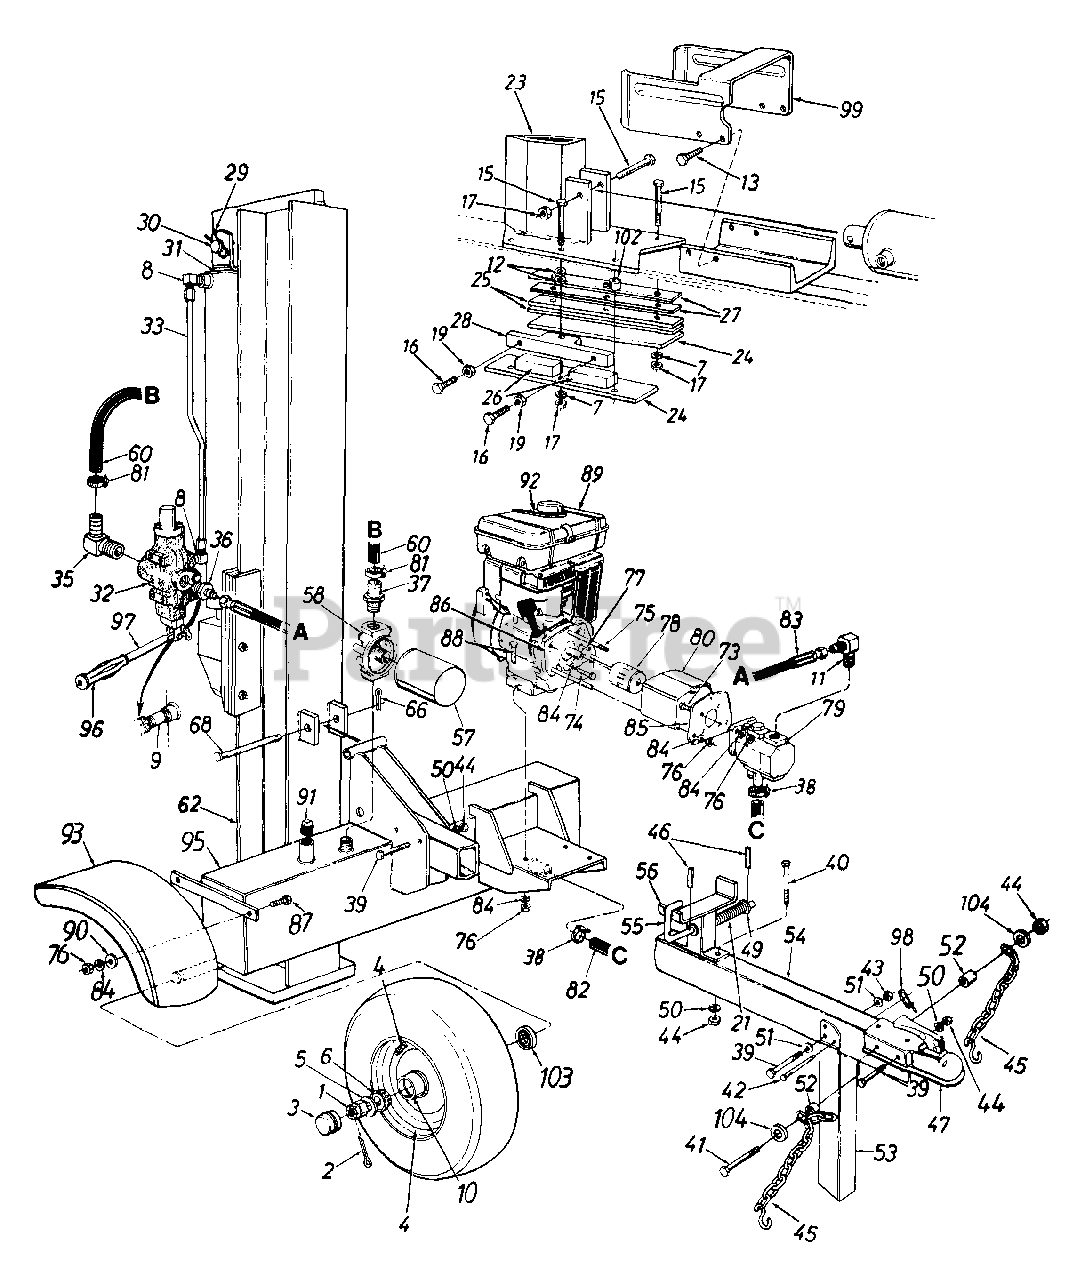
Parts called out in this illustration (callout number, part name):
1	Slotted Nut 3/4-16 Thd.
2	Cotter pin 5/32" Dia.
3	Hub Cap
4	Wheel Ass'y. Comp.
4	Tire Only
4	Rim Only
4	Air Valve Only
5	Fl-Wash. .76" I.D. x 1.5" O.D.
6	Bearing Cone
7	L-Wash. 1/2" I.D.
8	90° Solid Male Adaptor
9	Pipe Nipple 1/2 NPT
10	Bearing Cup
11	90° Male Adapter
12	Fl-Wash. .531" I.D. x .94" O.D.
13	Hex Cap Scr. 3/8-16 x 1" Lg.
15	Hex Bolt 1/2-20 x 2.75" Lg. (Grade 8)
16	Hex Bolt 3/8-24 x 1.5" Lg.
17	Hex L-Nut 1/2-20 Thd.
19	Hex Jam Nut 3/8-24 Thd. (Grade 5)
21	Comp. Spring 4" Lg.
23	Wedge Ass'y.
27	Adjustable Gib Shim
29	External Cotter Pin
30	Cylinder Mounting Pin
31	Hydraulic Cylinder
32	Control Valve
33	Metal Pressure Tube
35	Return Elbow
36	Adapter
37	3/4" Hose Barb.
38	Hose Clamp
39	Hex Bolt 3/8-16 x 3" Lg. (Grade 8)
40	Hex Bolt 3/8-16 x 4" Lg.
41	Hex Bolt 3/8-16 x 4.25" Lg. (Grade 5)
42	Clevis Pin 5/16 x 2.5" Lg.
43	Hex L-Nut 3/8-16 Thd.
44	Hex Nut 3/8-16 Thd.
45	Chain - Tow Hitch
46	Roll Pin
47	Hitch Coupler
49	Fl-Wash. .635" I.D. x .93" O.D.
50	L-Wash. 3/8" I.D.
51	Fl-Wash. .406" I.D. x .75" O.D.
52	Spacer .44" Lg.
55	Locking Rod
57	Filter Element
58	Filter Head
60	Return Hose 3/4" I.D. x 44" Lg.
68	Hinge Pin 1/2 x 4.8" Lg.
73	Hex Bolt 5/16-24 x 1" Lg.
74	Hex Bolt 5/16-24 x .62" Lg.
75	Hex Bolt 5/16-24 x 4" Lg.
76	Hex Nut 5/16-24 Thd.
77	Sq.-Key 3/16" x .75"
78	Flexible Coupling
79	Gear Pump
80	Coupling Shield
81	Hose Clamp 5/8"
82	Suction Hose
83	High Pressure Hydraulic Hose 48"
84	L-Wash. 5/16" I.D.
85	Rear Coupling Support Brkt.
86	Front Coupling Support Brkt.
87	Hex Bolt 5/16-24 x .75" Lg.
88	Hex Bolt 5/16-24 x 1.75" Lg.
89	Engine
90	Fl-Wash. .344" I.D. x .875" O.D.
91	L-Vent Pipe Plug
92	Spark Plug Boot
97	Control Handle
98	Spring Pin
102	Spacer 1/2" I.D. x .86" Lg.
103	Bearing Seal Only
104	Fl-Wash. 3/8" I.D. x .87" O.D.
